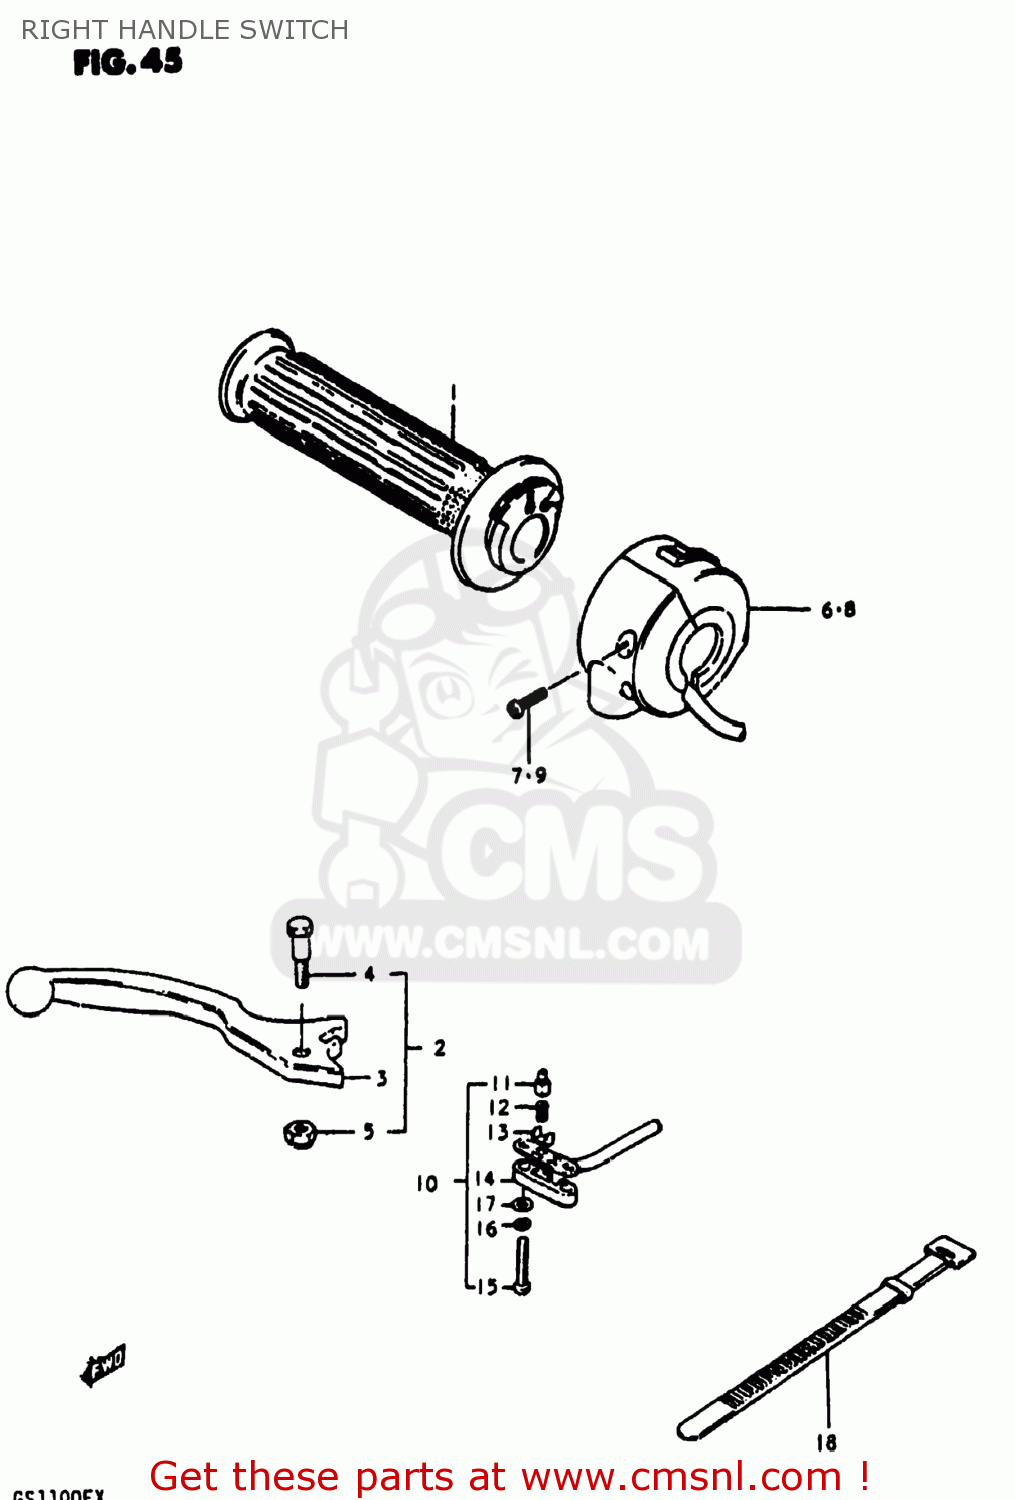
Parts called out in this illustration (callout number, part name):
1	GRIP,THROTTLE
2	LEVER ASSEMBLY,BRAKE
3	LEVER,BRAKE
4	BOLT
5	NUT 6MM
6	SWITCH ASSEMBLY,HANDLE,RIGHT
7	SCREW
8	SWITCH ASSEMBLY,HANDLE,RIGHT
9	SCREW
10	SWITCH ASSEMBLY
11	HOLDER
12	SPRING
13	PLATE
14	COVER,FR BK TERMINAL BASE
15	SCREW
16	LOCK WASHER
17	WASHER
18	CLAMP(L:120)
